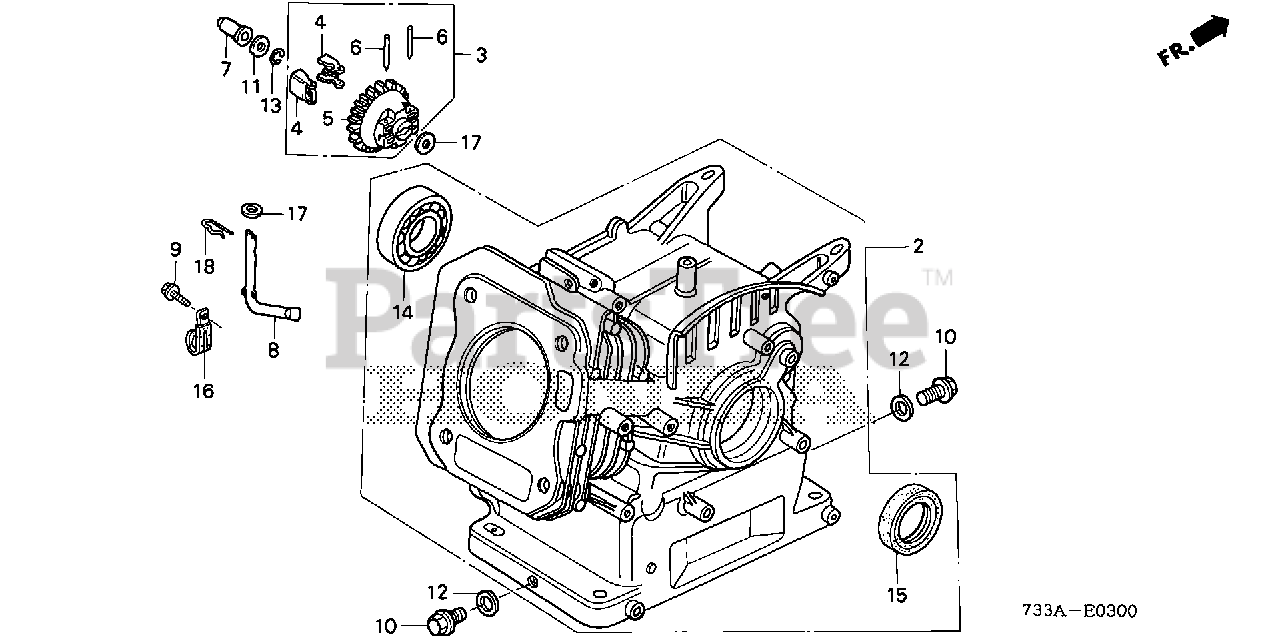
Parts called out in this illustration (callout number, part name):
2	CYLINDER ASSY.
2	CYLINDER ASSY. (STD)
3	GOVERNOR ASSY.
4	WEIGHT, GOVERNOR
5	HOLDER, GOVERNOR WEIGHT
6	PIN, GOVERNOR WEIGHT
7	SLIDER, GOVERNOR
8	SHAFT, GOVERNOR ARM
9	BOLT, FLANGE (6X12) (CT200)
10	BOLT, DRAIN PLUG
11	WASHER, THRUST (6MM)
12	WASHER, DRAIN PLUG (10.2MM)
13	CLIP, GOVERNOR HOLDER
14	BEARING, RADIAL BALL
15	OIL SEAL (22X35X6)
16	CLIP, WIRE HARNESS
17	WASHER, PLAIN (6MM)
18	PIN, LOCK (8MM)
